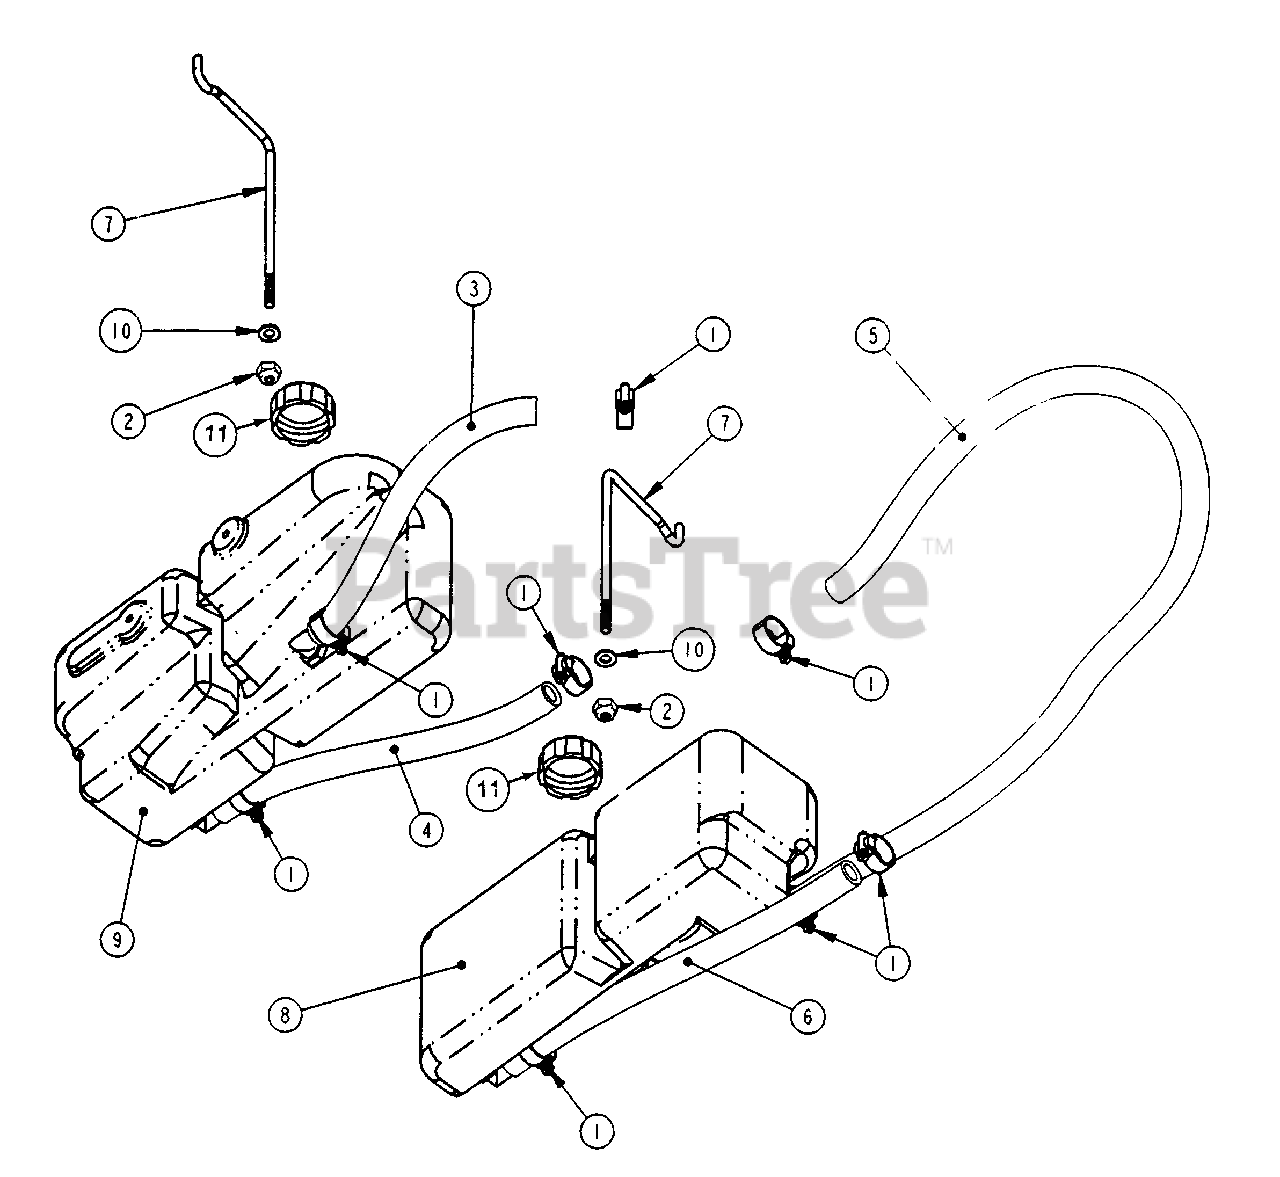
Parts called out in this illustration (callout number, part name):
1	CLAMP, Hose 13/16"
2	NUT, 5/16-18 HEX NYLON LOCK
3	HOSE, Rubber R.H. Front (.625 I.D. x 13-1/2" Long)
4	HOSE, Rubber R.H. Back (.625 I.D. x 16" Long)
5	HOSE, Rubber L.H. Front (.625 I.D. x 24" Long)
6	HOSE, Rubber L.H. Back (.625 I.D. x 18" Long)
7	BRACKET, Reservoir
8	RESERVOIR, L.H. Hydro
9	RESERVOIR, R.H. Hydro
10	WASHER, 11/32 I.D. x 11/16" O.D.
11	CAP, Reservoir
